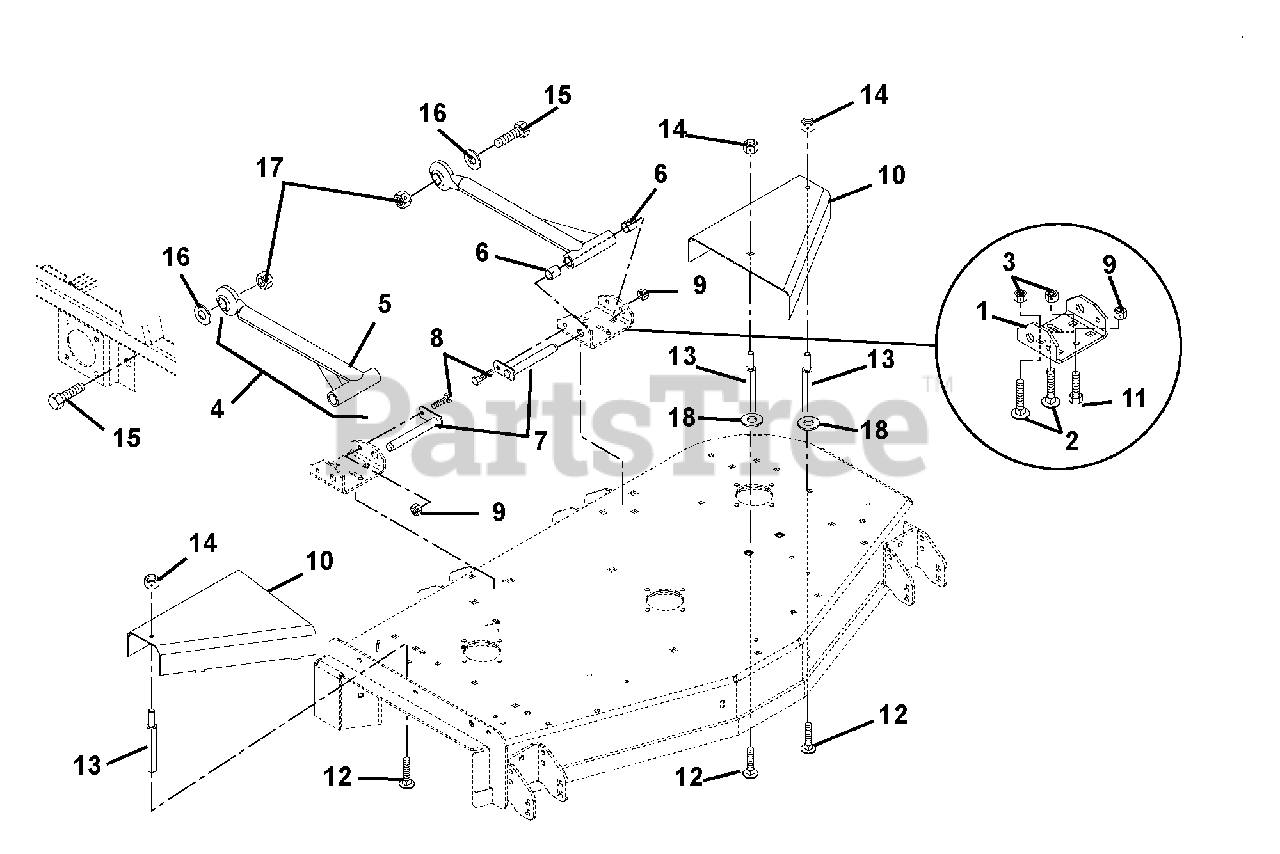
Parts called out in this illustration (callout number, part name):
1	Bracket, Mower Mounting (Rear)
2	Bolt, Round Head Square Neck .50-13 x .75 Grade 5
3	Nut, Locking Center Jam .50-13
4	Assembly, Mower Mounting Arm
5	Weldment, Mower Mounting Arm
6	Bearing .75 x .875 x 1.00
7	Weldment, Mower Mounting Pin
8	Bolt, Hex .38-16 x .88 Grade 5
9	Nut, Locking Top Flange .38-16
10	Guard, Pulley Left Hand
10	Guard, Pulley Right Hand
10	Guard, Right Hand Pulley
10	Guard, Left Hand Pulley
11	Bolt, Round Head Square Neck .38-16 x .75 Grade 5
12	Bolt, Round Head Square Neck .31-18 x .75
13	Standoff 2.75 x 5/16-18
14	Nut, Locking Top Flange .31-18
15	Bolt, Hex .875-9 x 2.75 Grade 5
16	Washer, Flat Steel .875 x 1.50 x .120
17	Nut, Locking Center .875-9
18	Washer, Flat Steel .328 x .87 x .179
